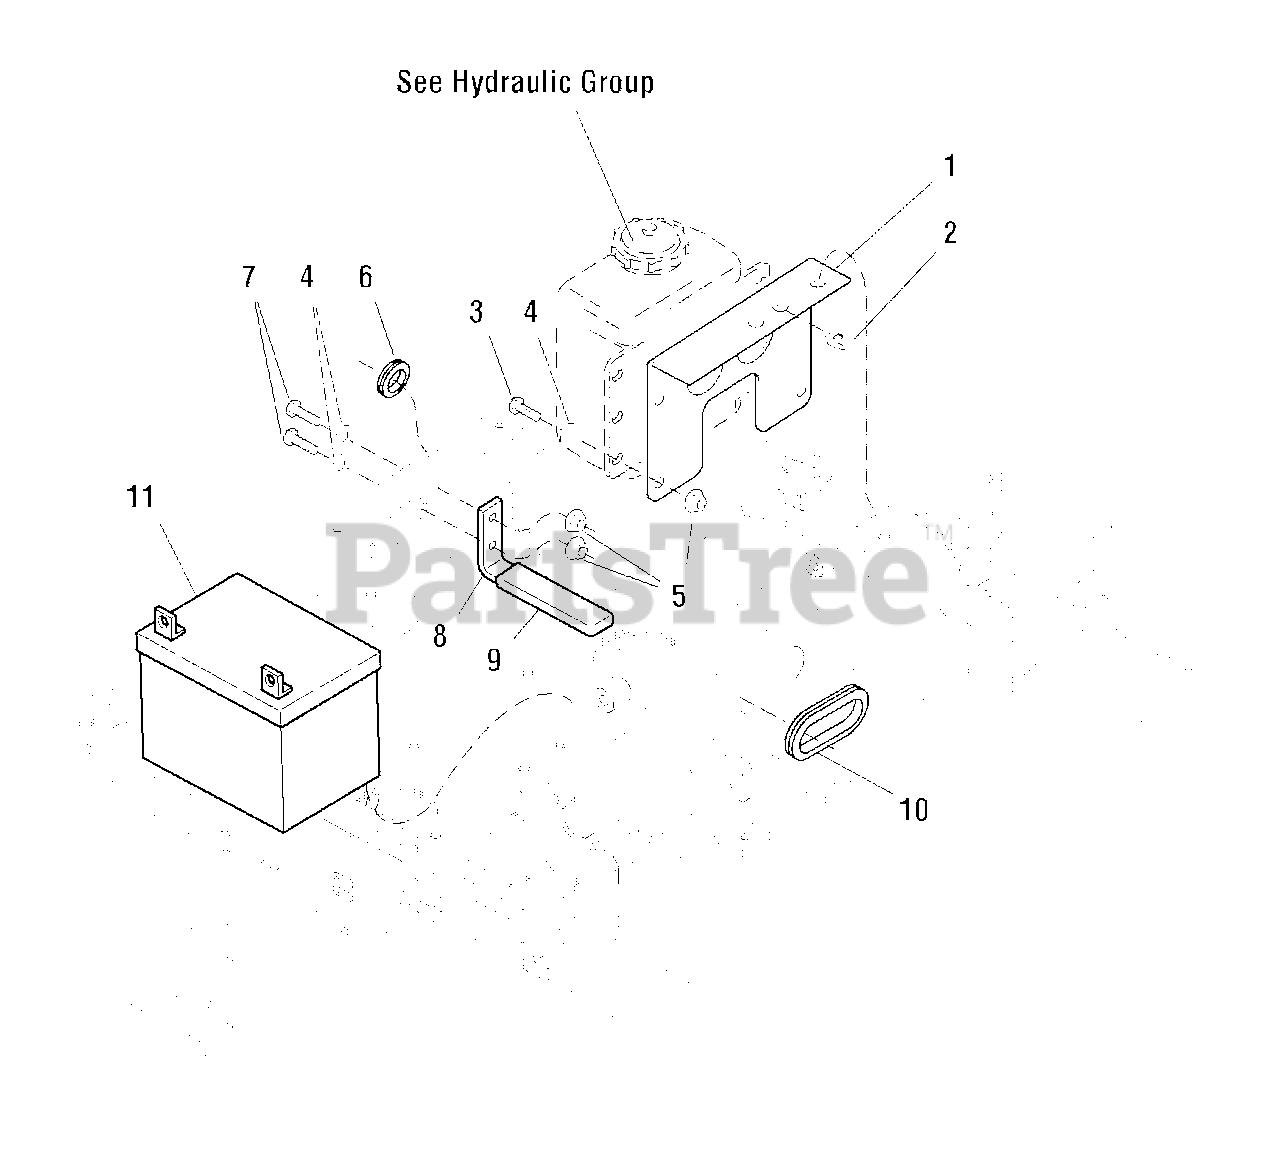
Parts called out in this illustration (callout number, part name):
1	MOUNT, Reservoir
2	BODY CLIP, 3/8-16
3	CAPSCREW, Hex Hd, 5/16-18 x 3/4
4	WASHER, 5/16
5	NUT, Hex, Serrated Flange, 5/16-18
6	GROMMET, 7/8
7	CAPSCREW, Hex Hd, 5/16-18 x 1
8	RETAINER, Battery
10	GROMMET, 3"
11	BATTERY
